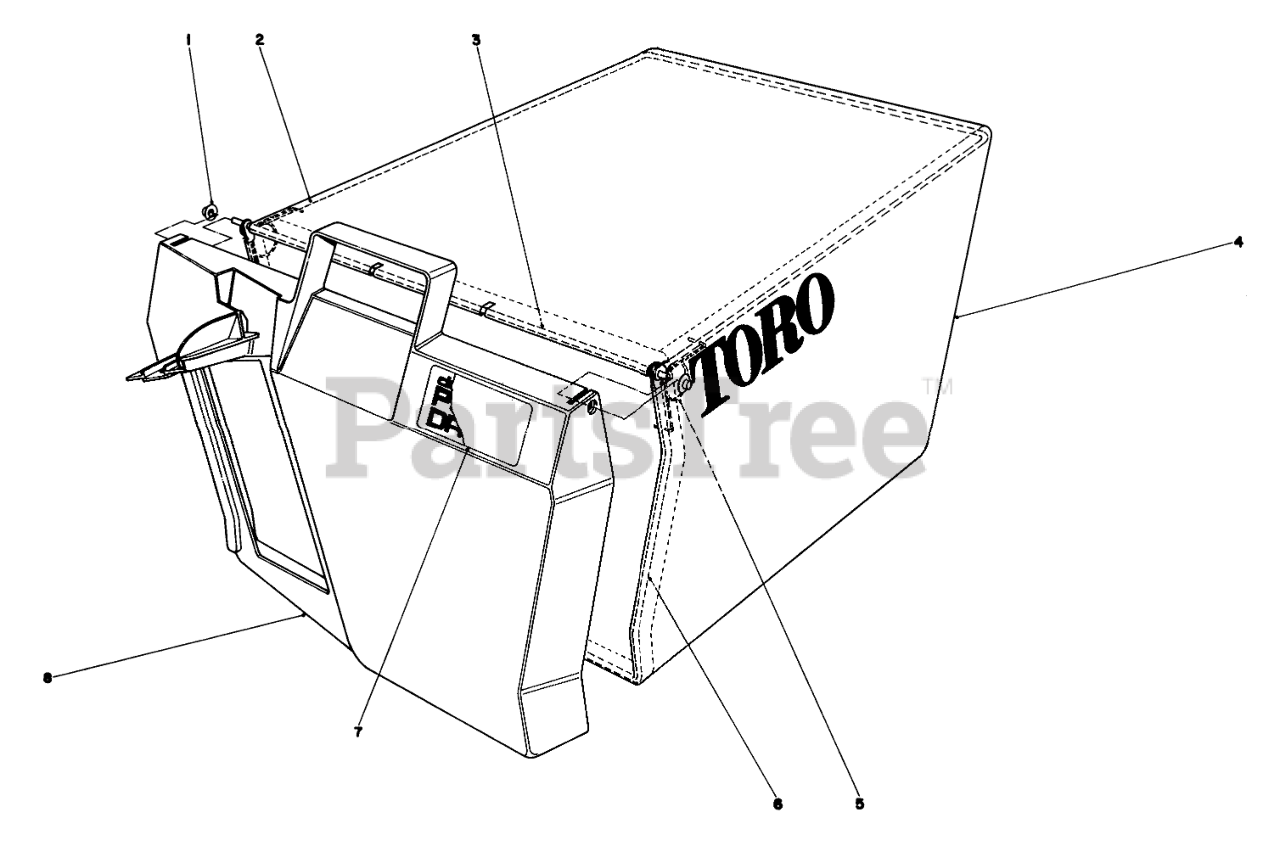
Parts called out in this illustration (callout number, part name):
1	NUT-PUSH
2	Bag Frame Upper
3	HINGE-DOOR, BAG
4	Bag
5	SPRING
6	Frame Bag
7	Decal Bag Door
8	Door Grass Bag
